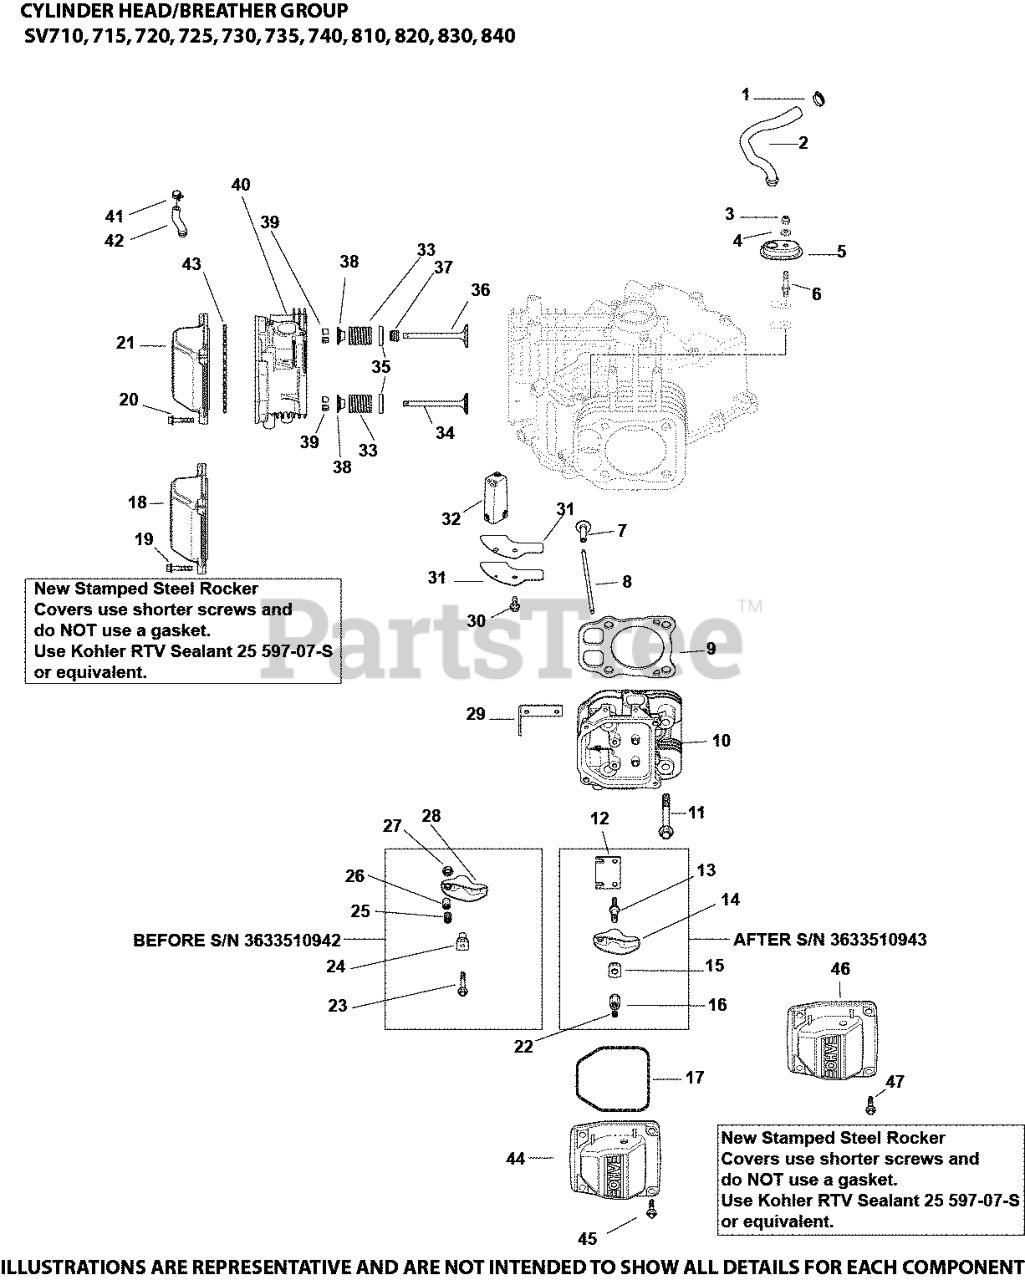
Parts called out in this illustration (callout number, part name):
1	CLAMP, HOSE (KM)-USE 25 237 31-S
2	KIT, BREATHER HOSE
3	NUT, LOCK M5X.8
4	WASHER, SEALING
5	KIT, BREATHER HOUSING
6	STUD, BREATHER COVER
8	ROD, PUSH
9	KIT, CYLINDER HEAD GASKET-USE 32 841 02-
10	KIT, #2 CYLINDER HEAD ASSEMBLY USE 32 318 20-S
11	SCREW, FLG M10X1.5X90
12	PLATE, GUIDE
13	STUD, ROCKER
14	ARM, ROCKER
15	PIVOT, ROCKER ARM
16	HEX NUT ASSEMBLY
18	COVER, ROCKER STAMPED STEEL
19	SCREW, PAN HEAD USE 25 086 660-S
20	SCREW, FLG M6X1.0X30
22	SCREW, SET
23	SCREW, FLG M6X1.0X45 USE 25 086 764-S
24	PIVOT, ROCKER ARM
25	SCREW, SET
26	NUT, HEX
27	NUT, M10X0.75
28	KIT, ROCKER ARM
29	STRAP, LIFT
30	SCREW,FLG THD FRM M6X1.0X16-(#25086397S)
31	GASKET, BREATHER COVER - DISC.
31	COVER, BREATHER
32	FILTER, BREATHER
33	SPRING, VALVE - USE 25 089 17-S
34	VALVE, EXHAUST (STD) - USE 32 016 01-S
35	RETAINER, SPRING
36	VALVE, INTAKE (STD)
37	SEAL, VALVE STEM - (#2503214S)
38	CAP, VALVE SPRING
39	KIT, RETAINER
40	KIT, #1 CYLINDER HEAD ASSEMBLY USE 32 318 19-S
41	CLAMP, HOSE
42	KIT, FUEL PUMP HOSE(PLASTIC COVERS)
46	COVER, ROCKER (STEEL)- (#3275542S)
47	SCREW, PAN HEAD USE 25 086 660-S
